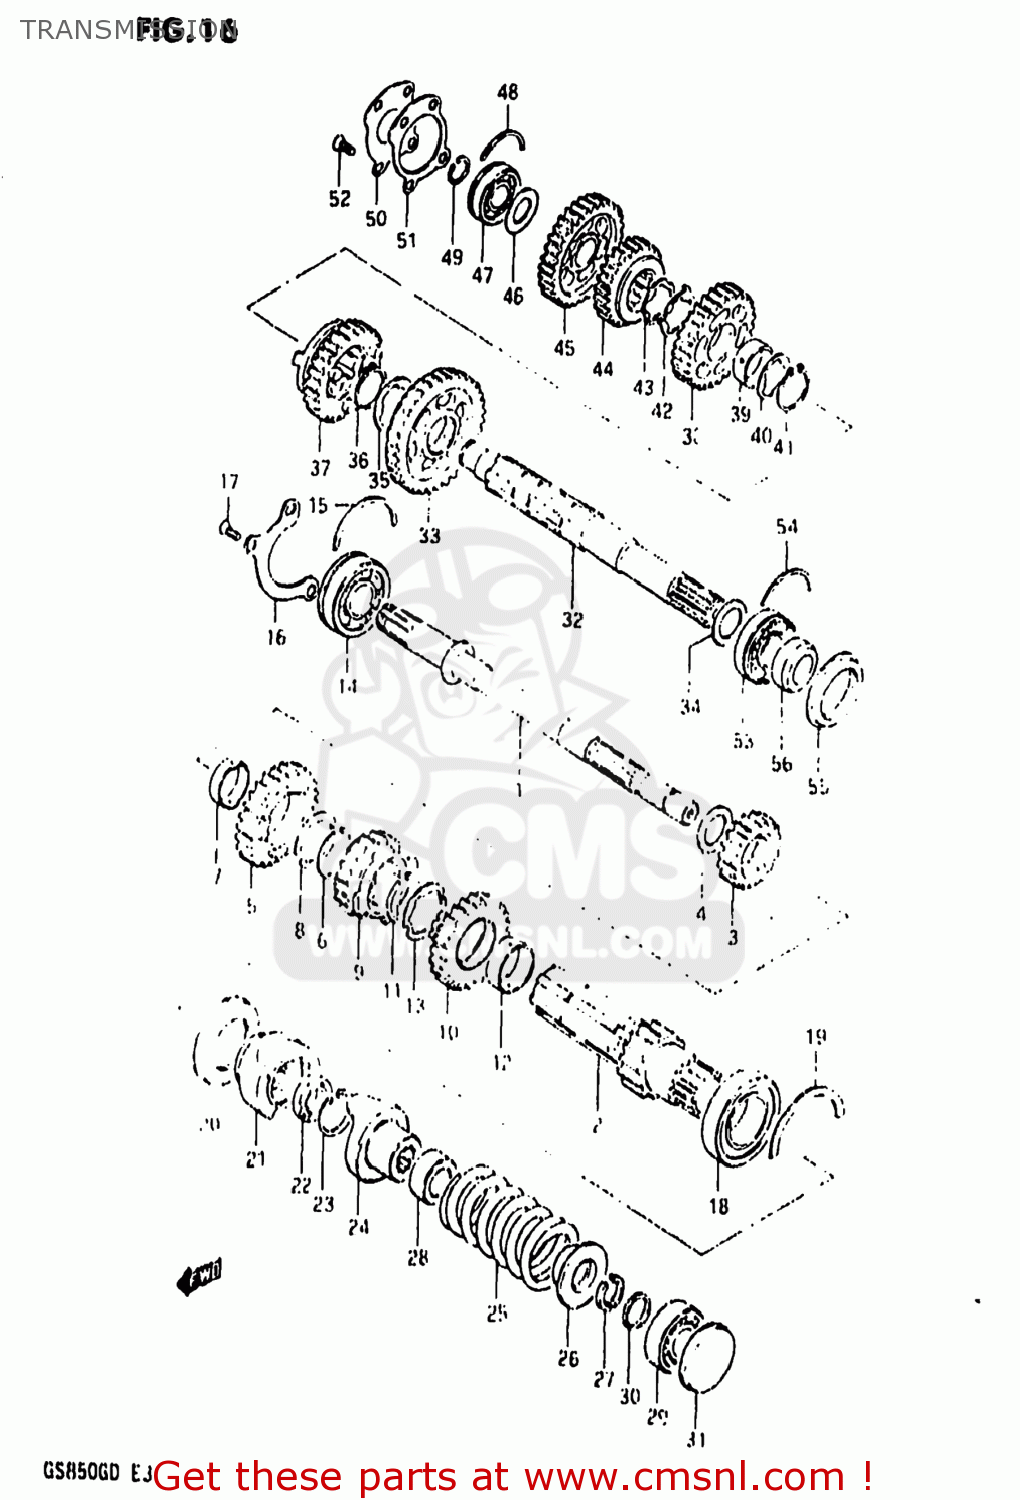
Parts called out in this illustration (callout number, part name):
1	SHAFT,COUNTER
2	SHAFT,OUTER COUNTER
3	GEAR,SECOND DRIVE
4	WASHER (21X35X2)
5	GEAR,5TH DRIVE(NT:26)
6	RING,SNAP
7	SPACER,DRIVE GEAR
8	LOCK WASHER,5TH DR GEAR SPACER
9	GEAR,THIRD DRIVE
10	GEAR,FOURTH DRIVE
11	RING,SNAP
12	SPACER,DRIVE GEAR
13	LOCK WASHER,5TH DR GEAR SPACER
14	BEARING(25X62X17)
15	C-RING
16	RETAINER,CNTR SHAFT BEARING
17	SCREW
18	BALL BEARING 32X58X13
19	C-RING
20	SEAL,OIL(40X58X7)
21	DOG,OUTPUT CAM
22	SEAL,OIL(20.6X31X6)
23	CIRCLIP
24	DOG,INPUT CAM
25	SPRING
26	STOPPER,CAM DOG SLIDING
27	STOPPER,CAM DOG
28	GUIDE,CAM DOG SPRING
29	BEARING
30	SPACER (17X21X3.5)
31	PLUG
32	SHAFT,DRIVE
33	GEAR,FIRST DRIVEN
34	WASHER, LH
35	WASHER,LOCK
36	CIRCLIP
37	GEAR,FOURTH DRIVEN
38	GEAR,THIRD DRIVEN
39	BUSH,3RD DRIVEN GEAR
40	WASHER,LOCK
41	CIRCLIP
42	WASHER
43	WASHER,LOCK
44	GEAR,FIFTH DRIVEN
45	GEAR,SECOND DRIVEN
46	WASHER
47	BEARING(20X47X14)
48	C RING
49	CIRCLIP
50	PLATE,DRIVESHAFT
51	GASKET,DRIVESHAFT PLATE (MCA)
52	SCREW
53	BEARING
54	C RING
55	SEAL,OIL(35X52X6)
56	SPACER,DRIVESHAFT,LEFT
